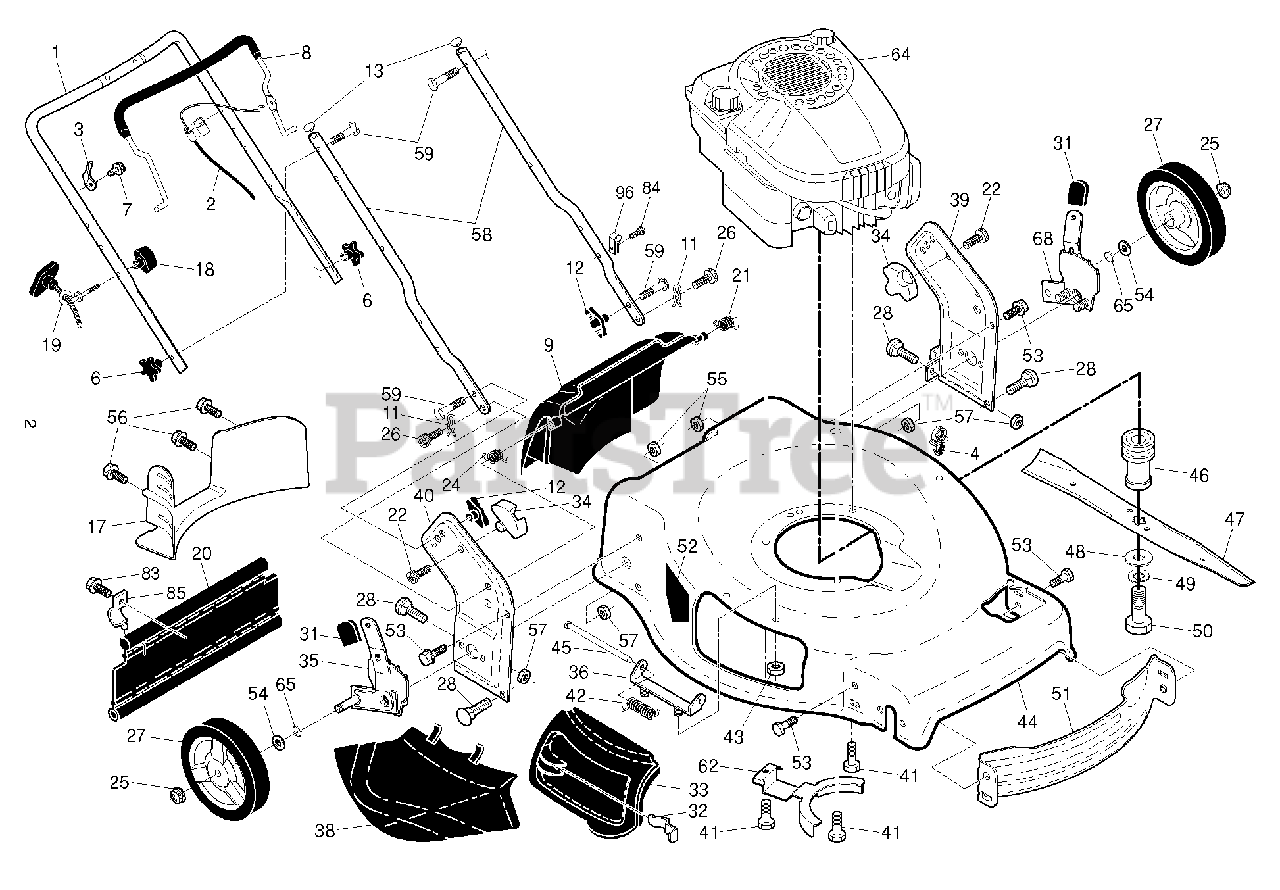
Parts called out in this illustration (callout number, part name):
1	HANDLE.UP.DST.SS/VS.FG/RGD.CRE
2	CABLE.MZR.FGD.PLUS
3	BRACKET.UPSTOP.RT
6	KNOB.HANDLE.PLASTIC.STAR.BLACK
8	RP BAIL.OVER.MOLD.STRAIGHT.ORG
9	DOOR.REAR.ASM.22+.HUSQ.FG/RGD
11	COTTER.HAIRPIN.DOOR/HANDLE.PIV
12	KNOB, DEFLECTOR
13	PLUG.PLASTIC.7/8".14-20.GAUGE
17	BAFFLE.22PLUS.FGD.REAR.
18	T-KNOB.NEW ROPE GUIDE
19	GUIDE.ROPE.BLK.ZINC.CHROM
20	SKIRT.REAR.22PLUS.RGD/FGD.NEW
21	SPRING.LH.BLACK
22	SCREW.PAN.HEAD.#10
24	SPRING.RH.GRAY
25	NUT.HEX.FLANGE.3/8-16.LO(3 2)
26	SCREW,DOOR/HANDLE.PIVOT
27	WHEEL & TIRES ASSY, FRONT
28	BOLT.CARRIAGE.LN.5/16-18X.5/8
31	SELECTOR KNOB
32	LATCH.DOOR.ZINC
33	DOOR.MULCH.22 PLUS.HUSQ.GREY
34	BRACKET.GRASSBAG.ATTACHING.BLK
35	ADJUSTER.ASM.9POS.LW.RR/RGD.
36	BRACKET.ASM.HINGE.21.FWGD.
38	DEFLECTOR.CLIPPING.22.BLACK
39	BRACKET.ASM.HANDLE.LT.22+.GREY
40	BRACKET.ASM.HANDLE.RT.22+.GREY
41	BOLT 3/8-16X1-1/8
42	SPRING.TORSION
43	NUT.HEX.FLANGE.1/4
44	HOUSING.22+.FWD.MC.ZWO.ORANGE.
45	ROD.HINGE.21
46	ADAPTOR BLADE 25MM STAR
47	BLADE.22+4N1.2PIN.5STAR.(P07)
48	WASHER,HARDEN
49	LOCKWASHER
50	SCREW, HEX HD 3/8-24 X 1-3/8
51	BAFFLE.FRONT.22.PLUS
52	DANGER DECAL
53	BOLT.5/16HEX.WHS.HD
55	NUT.HEX.FLANGE.1/4
56	SCREW.HX.13X.750
57	NUT.FLANGE.5/16
58	HANDLE.LOWER.22+BT.2PC.GRY
59	BOLT, HANDLE 5/16-18X1.75
62	BRACKET.ENG/BELTKEEPER
65	O-RING..070X.487.NEOPRENE
68	ADJUSTER.ASM.9POS.LW.RL/RGD.FR
83	TAPPING SCREW
84	FASTENER.PUSH.O.250X0.783
85	BRACKET.SKIRT.22+.BZP
96	CLIP.CABLE.BLK
